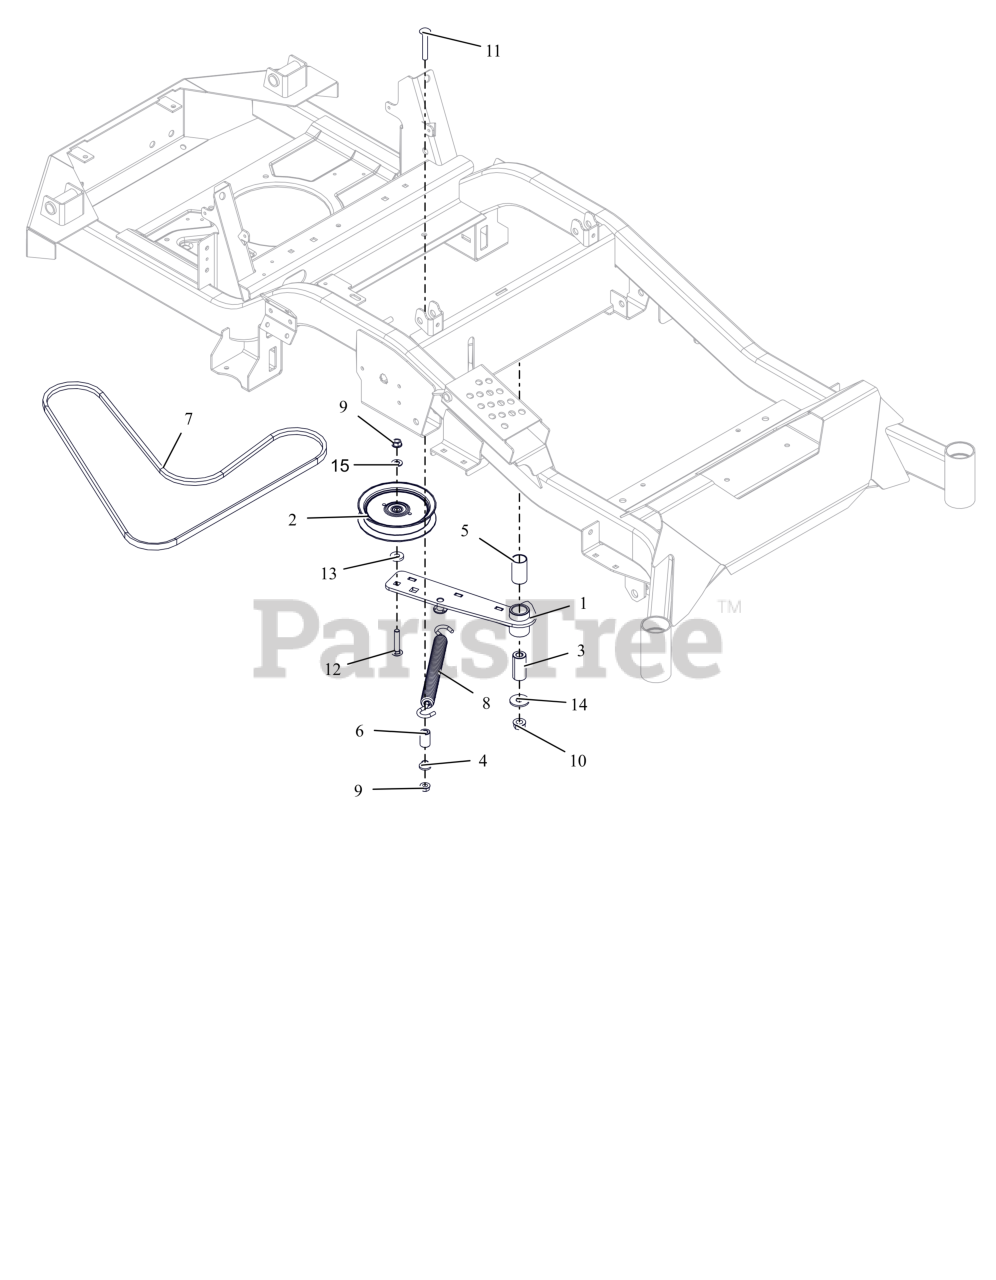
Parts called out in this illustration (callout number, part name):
1	WLDMT, HYDRO DRIVE IDLER ARM (BLACK)
2	IDLER, FLAT 5.00"
3	BSHG, SPCR .502X.997X2.03 PM
4	BSHG-FLG .385X.500X.875X.406
5	BSHG, 1.00X1.125X1.937
6	BUSHING, SLV .380X.750X1.190
7	V-BELT, 4L-WRAPPED
8	SPRING, EXTENSION
9	NUT-LK-TOP-FLG .38-16 ZC120
10	NUT-LK-TOP-FLG .500-13 GF ZCC
11	BLT, RHSSN.38-16X2.50 G5 ZCC
12	BLT, RHSN .38-16X2.00 G5 ZCC
13	WSHR, FLT .406X1.00X.188 ZCC
14	WSHR-FL-STL.511X1.44X.125ZC120
15	WSHR,FLT .406X.812X.065 ZCC
